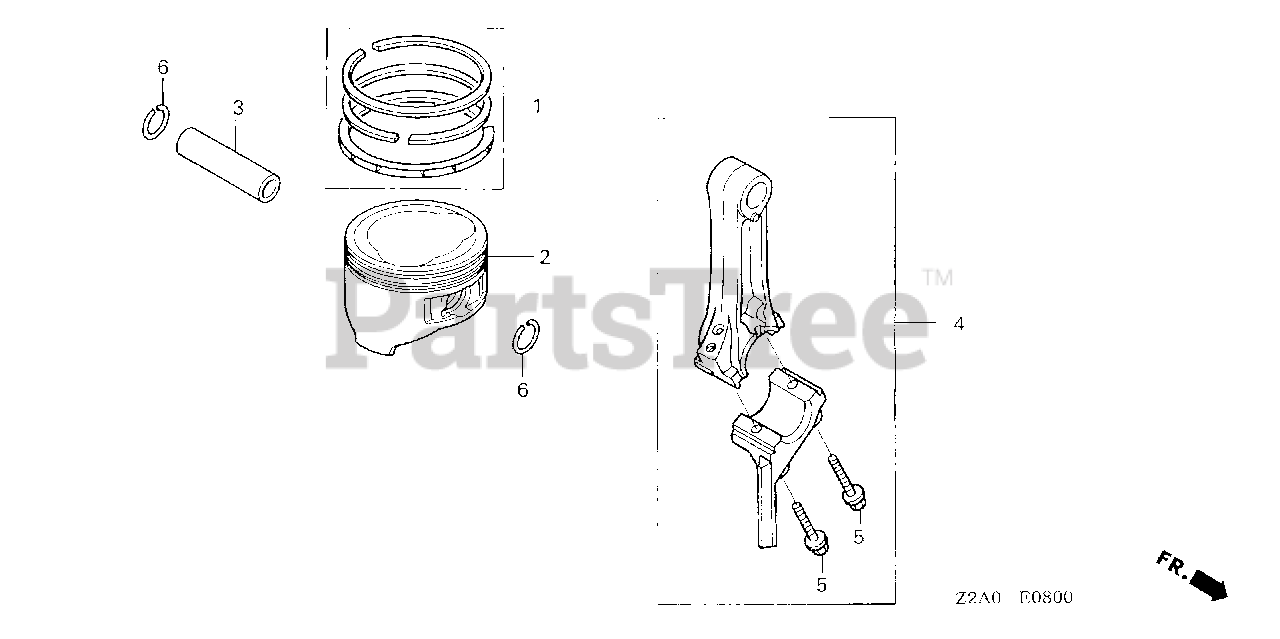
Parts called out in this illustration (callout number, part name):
1	RING SET, PISTON (STD) (TPR)
2	PISTON
3	PIN, PISTON
4	ROD ASSY., CONNECTING
5	BOLT, CONNECTING ROD
6	CLIP, PISTON PIN (13MM)
